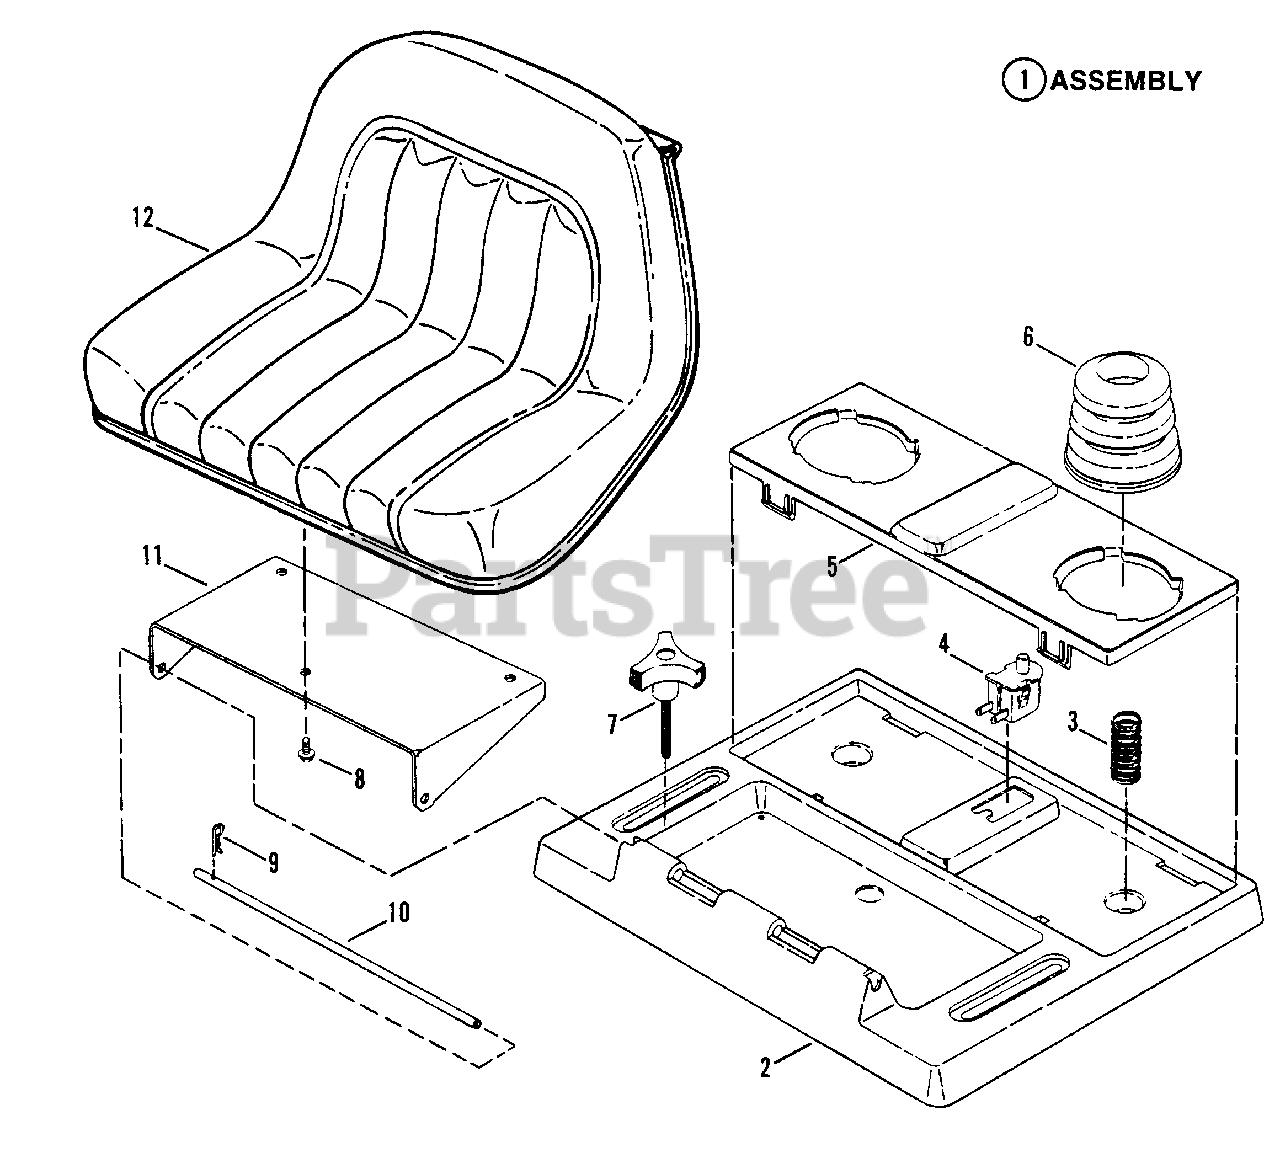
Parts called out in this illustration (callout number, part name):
1	ASSEMBLY, Seat Support (Includes 2, 4, 5, & 2 item 3)
2	SUPPORT, Seat
3	SPRING
4	SWITCH, Seat NC
5	HOLDER, Cushion
6	CUSHION, Seat
7	KNOB, Seat Adjustment 5/16-18MX2
8	BOLT, 5/16-18 x 1/2" Hex Flange Lock
9	PIN, Hair 1.12"
10	ROD, Seat Hinge
11	BRACKET, Seat Support
12	SEAT, Operator's
